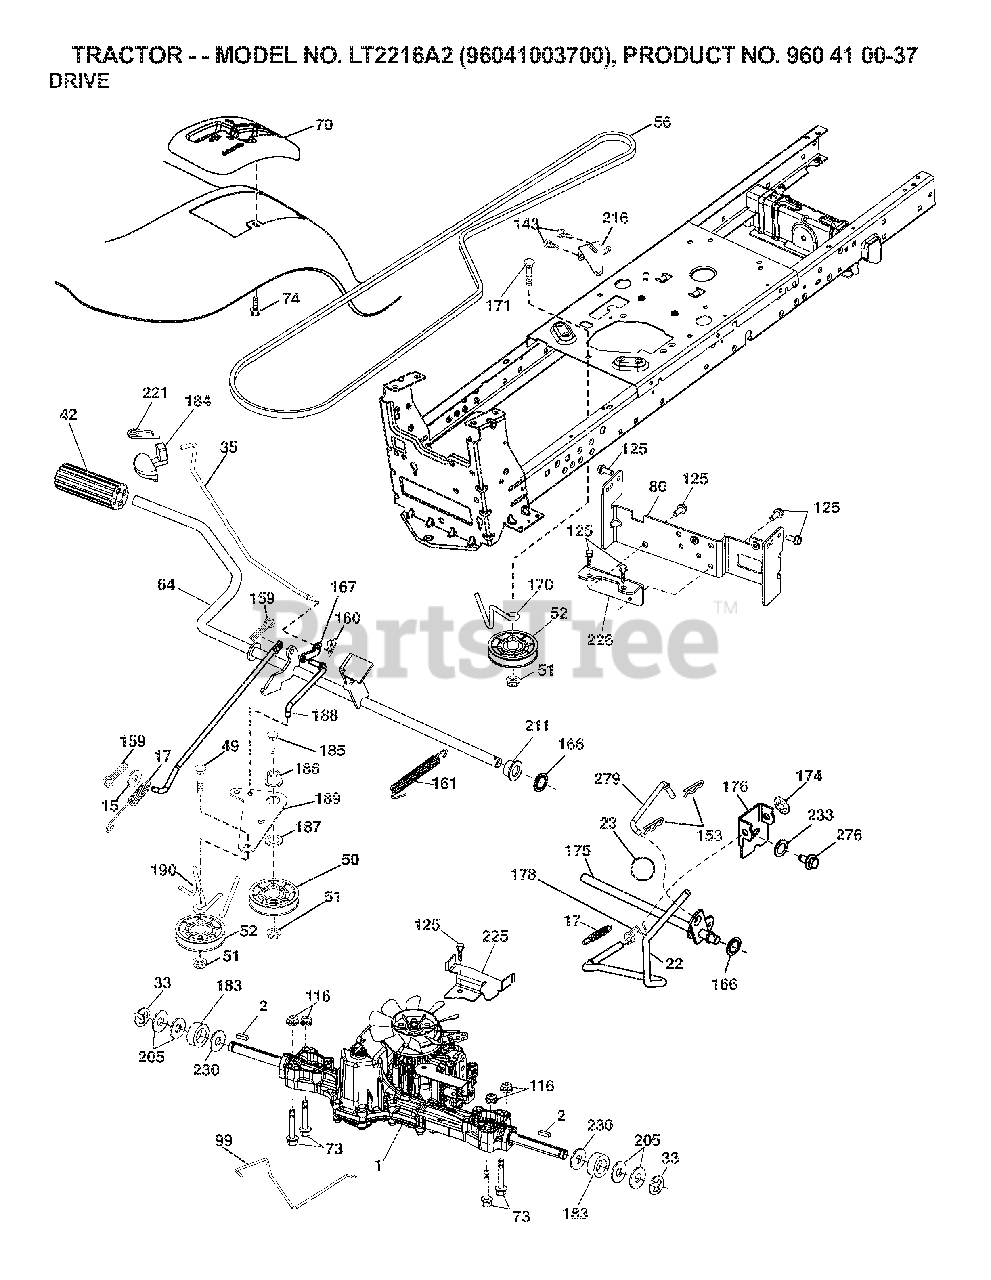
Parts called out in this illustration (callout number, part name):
1	TRANSAXLE.K46A
2	SQUARE KEY
17	SPRING.BRAKE.K46.GREEN
22	ROD.SHIFT.FENDER.TLT.2006
23	PISTOL KNOB
29	ROD.BRAKE.K46
33	E-RING LT
35	ROD.BRAKE.PARKING.LT.T
42	PEDAL COVER T
49	BOLT
50	IDLER.FLAT.910.OFFSET
51	NUT LOCK FLG 3/8-16 UNC
52	IDLER.V-GROOVE.910.OFFSET
64	SHAFT.ASM.PEDAL.BRAKE.
70	CONSOLE.SHIFT.STL.HYD.BLACK
73	BOLT HEX 5/16-18 GR 5
74	SCREW.HI-LO.CONSOLE
80	STRAP.TORQUE.HG3000/K46
99	ROD ASM BYPASS
116	NUT LOCK HEX FLANGE 5/16-18
125	SCREW
143	SCREW LT
153	RETAINER M
159	COTTER PIN
160	RETAINER CLIP
161	SPRING.RETURN.CLUTCH.2006
166	NUT.PUSH.625.2006
167	LATCH.BRAKE.SPRING
170	KEEPER.V-IDLER.CENTER.
171	BOLT
174	NUT.PUSH.500.2006
175	SHAFT ASM SHIFT
176	ARM.CLEVIS.ROD.SHIFT
178	SPRING.SHIFT.GT2006
183	SPACER AXLE
184	HANDLE.PAKRING.BRAKE.
185	BOLT
186	SPACER.RETAINER
187	WASHER 12/32X2X10GA
188	LINK.CLUTCH.GROUND.DRIVE
189	BELLCRANK.GROUND.DRIVE.TEX.
190	KEEPER.BELLCRANK.DRIVE
211	BUSHING.SHAFT.BRAKE.HAND
216	BRACKET.PULLEY.IDLER.W/TEX
221	RETAINER.SPRING.CLIP.H
225	KEEPER.BELT.TRANSAXLE.K46
226	BRACKET.MOUNT.TORQUE.K46.TLT
230	WASHER.HARDENED
233	WASHER SERRATED
276	BOLT FIN HEX 7/16-14 X 1
279	LINK SHIFT
